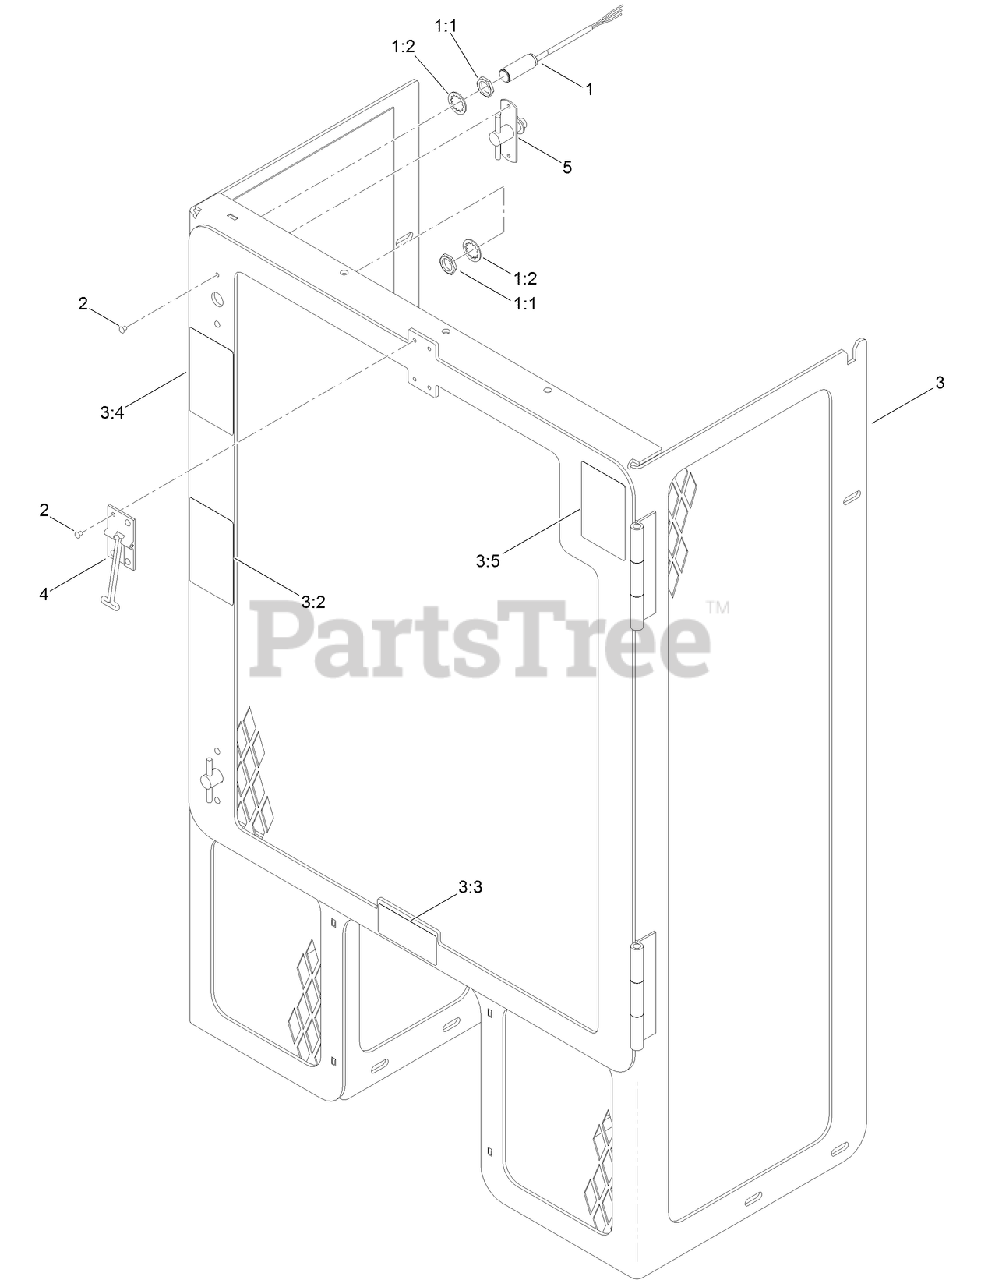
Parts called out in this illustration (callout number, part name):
1	PROXIMITY SWITCH ASM
1:1	NUT-HEX
1:2	WASHER-LOCK, INTERNAL TOOTH
2	RIVET-POP
3	STAKEDOWN COVER ASM
3:2	DECAL-DANGER, IMPACT HAZARD
3:3	DECAL-DANGER, ENTANGLEMENT
3:4	DECAL-WARNING, ENTANGLEMENT
3:5	DECAL-DANGER, HAZARDOUS AREA
4	LATCH-RETAINING
